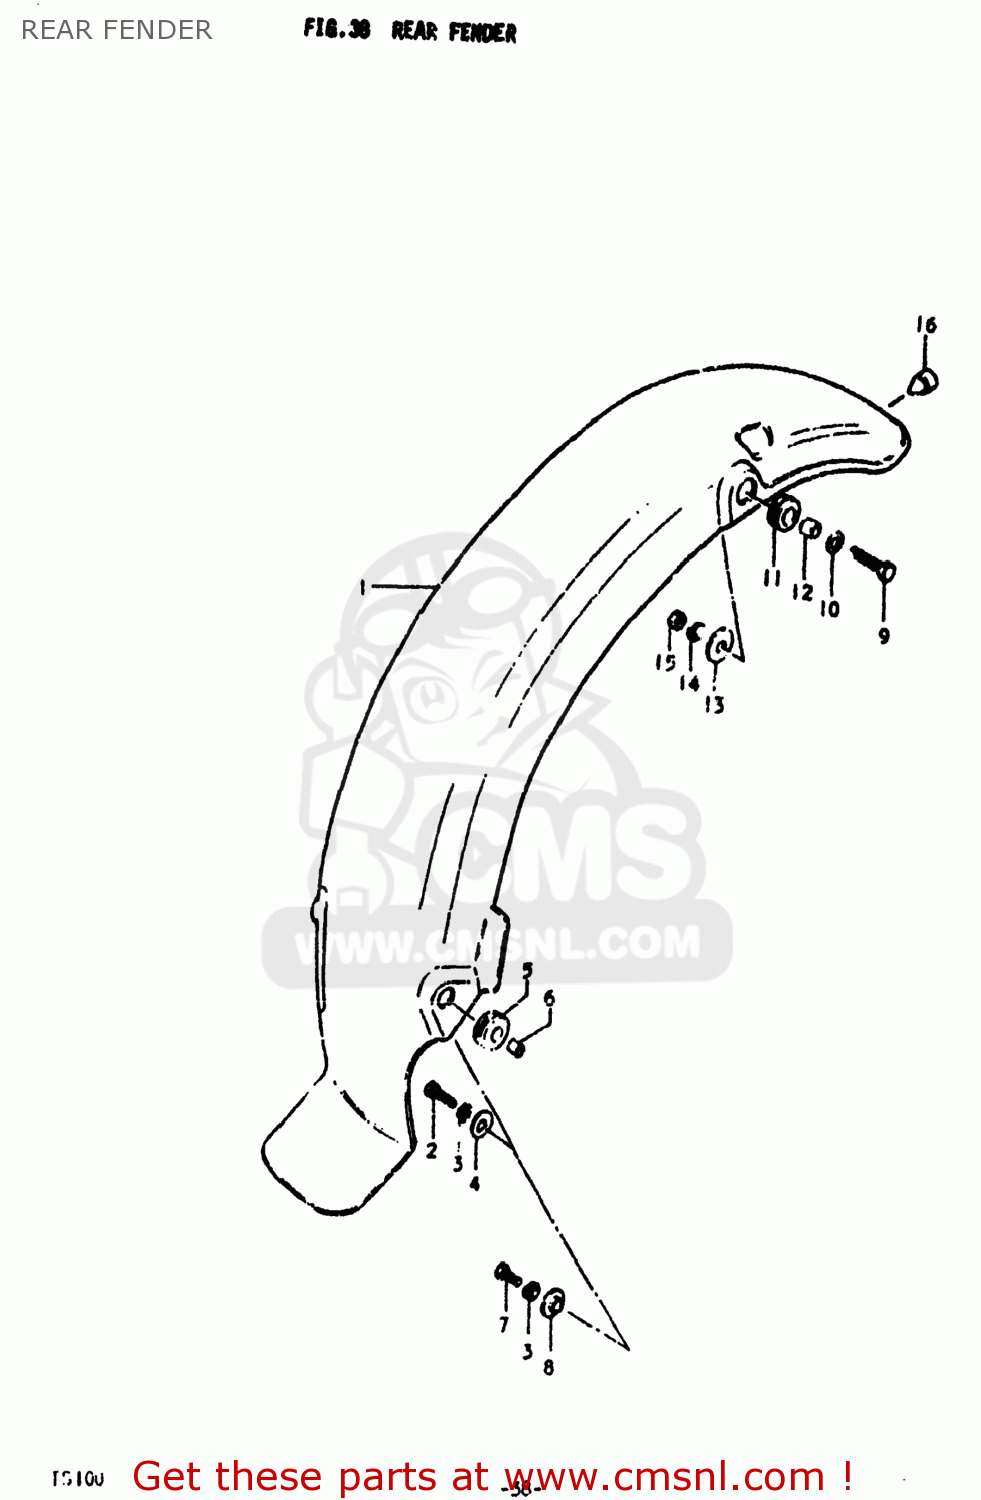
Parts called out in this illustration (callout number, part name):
1	FENDER,REAR
2	BOLT
3	LOCK WASHER
4	WASHER (6.5X20X1.2)
5	CUSHION
6	SPACER (6.3X9.1X6.7)
7	BOLT, UPPER
8	WASHER
9	BOLT
10	WASHER
11	CUSHION
12	SPACER (8.2X12X7.5)
13	WASHER(8.5X26X1.2)
14	LOCK WASHER
15	NUT
